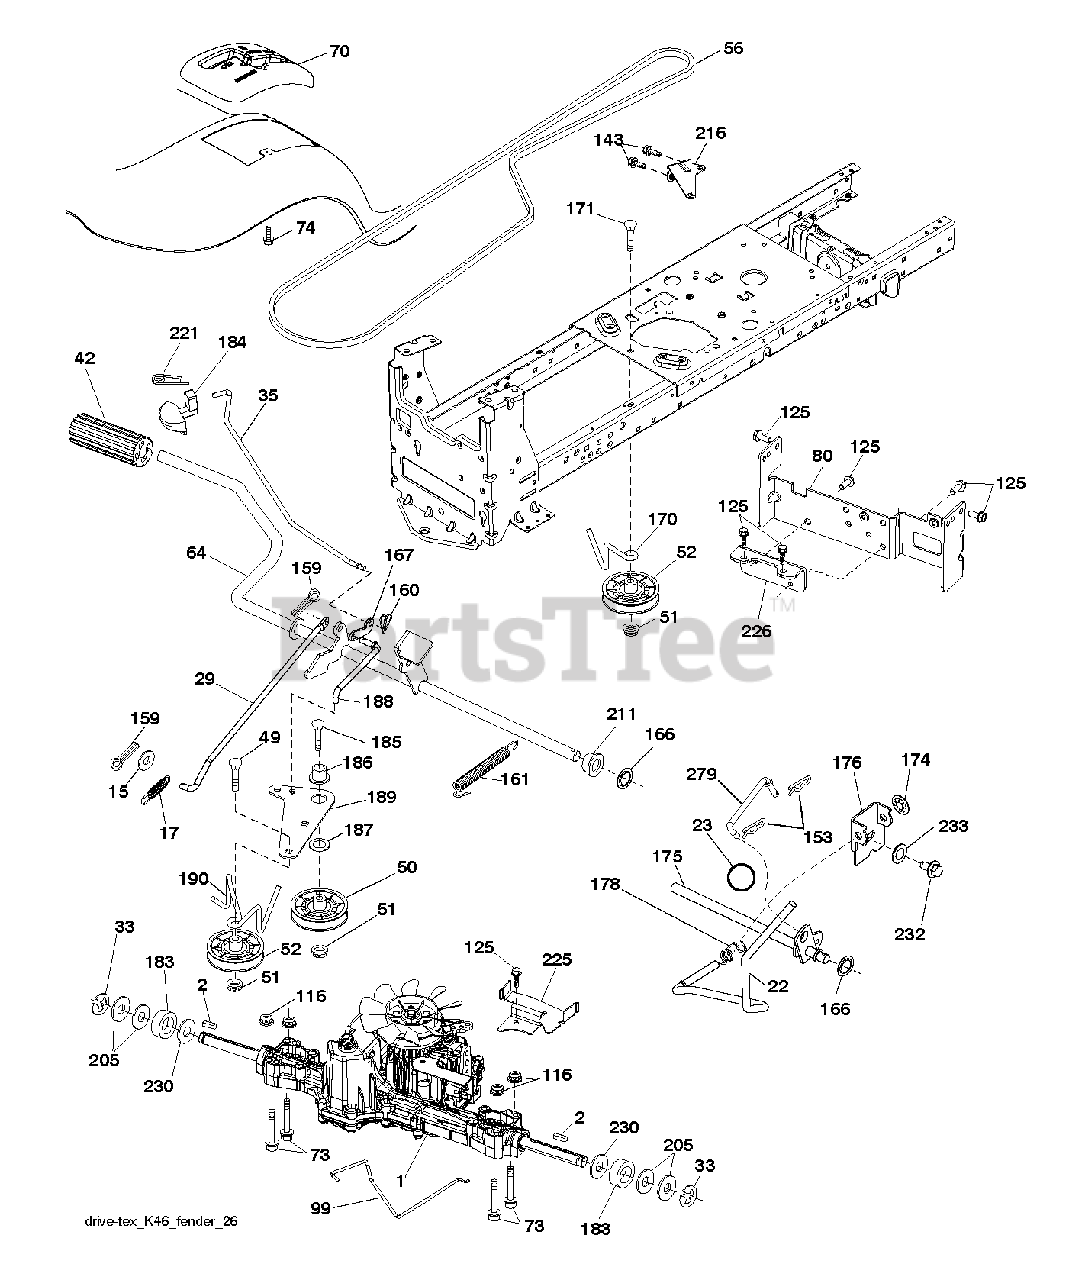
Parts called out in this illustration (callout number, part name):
2	SQUARE KEY
17	SPRING.BRAKE.K46.GREEN
22	ROD.SHIFT.FENDER.TLT.2006
23	PISTOL KNOB
29	ROD.BRAKE.K46
33	E-RING LT
35	ROD.BRAKE.PARKING.LT.T
42	PEDAL COVER T
49	BOLT
50	IDLER.FLAT.910.OFFSET
51	NUT LOCK FLG 3/8-16 UNC
52	IDLER.V-GROOVE.910.OFFSET
64	SHAFT.ASM.PEDAL.BRAKE.
70	CONSOLE.SHIFT.STL.HYD.BLACK
73	BOLT HEX 5/16-18 GR 5
74	SCREW.HI-LO.CONSOLE
80	STRAP TORQUE
99	ROD.SPRING.BYPASS.K46.LT.Z
116	NUT LOCK HEX FLANGE 5/16-18
125	SCREW
153	RETAINER M
159	COTTER PIN
160	RETAINER CLIP
161	SPRING, RETURN LT
166	NUT.PUSH.625
167	LATCH.BRAKE.SPRING
170	KEEPER.V-IDLER.CENTER.
171	BOLT
174	NUT.PUSH.500.2006
175	SHAFT ASM SHIFT
176	ARM.CLEVIS.ROD.SHIFT
178	SPRING.SHIFT.GT2006
183	SPACER AXLE
184	HANDLE.PAKRING.BRAKE.
186	SPACER.RETAINER
187	WASHER 12/32X2X10GA
188	LINK.CLUTCH.GROUND.DRIVE
189	BELLCRANK.GROUND.DRIVE.TEX.
190	KEEPER.BELLCRANK.DRIVE
211	BUSHING.SHAFT.BRAKE.HAND
216	BRACKET.PULLEY.IDLER.W/TEX
221	RETAINER.SPRING.CLIP.H
225	KEEPER.BELT.TRANSAXLE.K46
226	BRACKET.MOUNT.TORQUE.K46.TLT
230	WASHER.HARDENED
232	BOLT FIN HEX 7/16-14 X 1
233	WASHER SERRATED
279	LINK SHIFT
